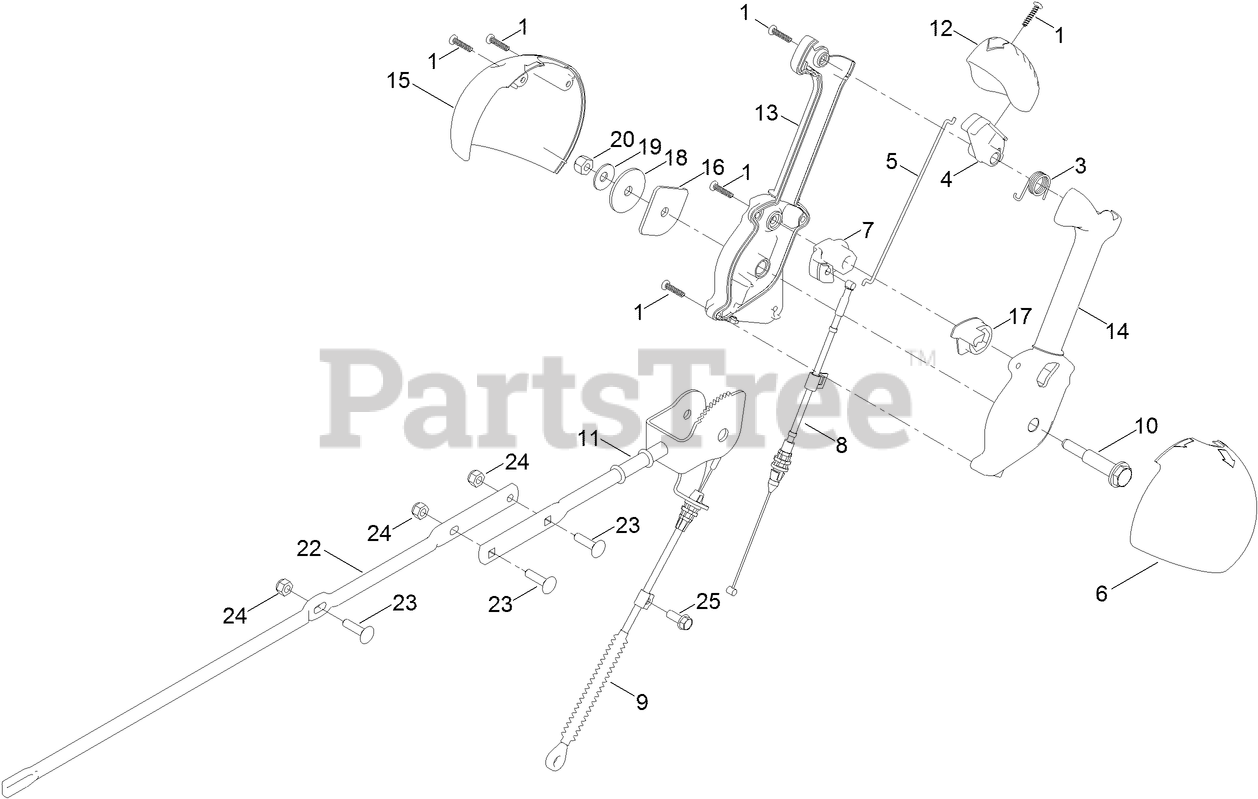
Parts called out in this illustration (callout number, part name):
1	SCREW-PPH
3	SPRING-TORSION
4	TRIGGER-LATCH
5	LINK-LATCH
6	COVER-LEVER, CHUTE (LH)
7	LEVER-CABLE, DEFLECTOR
8	CABLE-RELEASE, CHUTE
9	CABLE-CONTROL, DEFLECTOR
10	SCREW-SHOULDER
11	CHUTE CONTROL ROD
12	CAP-LEVER
13	LEVER-CONTROL, CHUTE (RH)
14	LEVER-CONTROL, CHUTE (LH)
15	COVER-LEVER, CHUTE (RH)
16	PLATE-FRICTION
17	PAWL-LATCH
18	WASHER-NYLON
19	WASHER-BELLEVILLE
20	NUT-LOCK, NI
22	ROD-CHUTE
23	SCREW-CARR
24	NUT-LOCK, NI
25	SCREW-HWH
